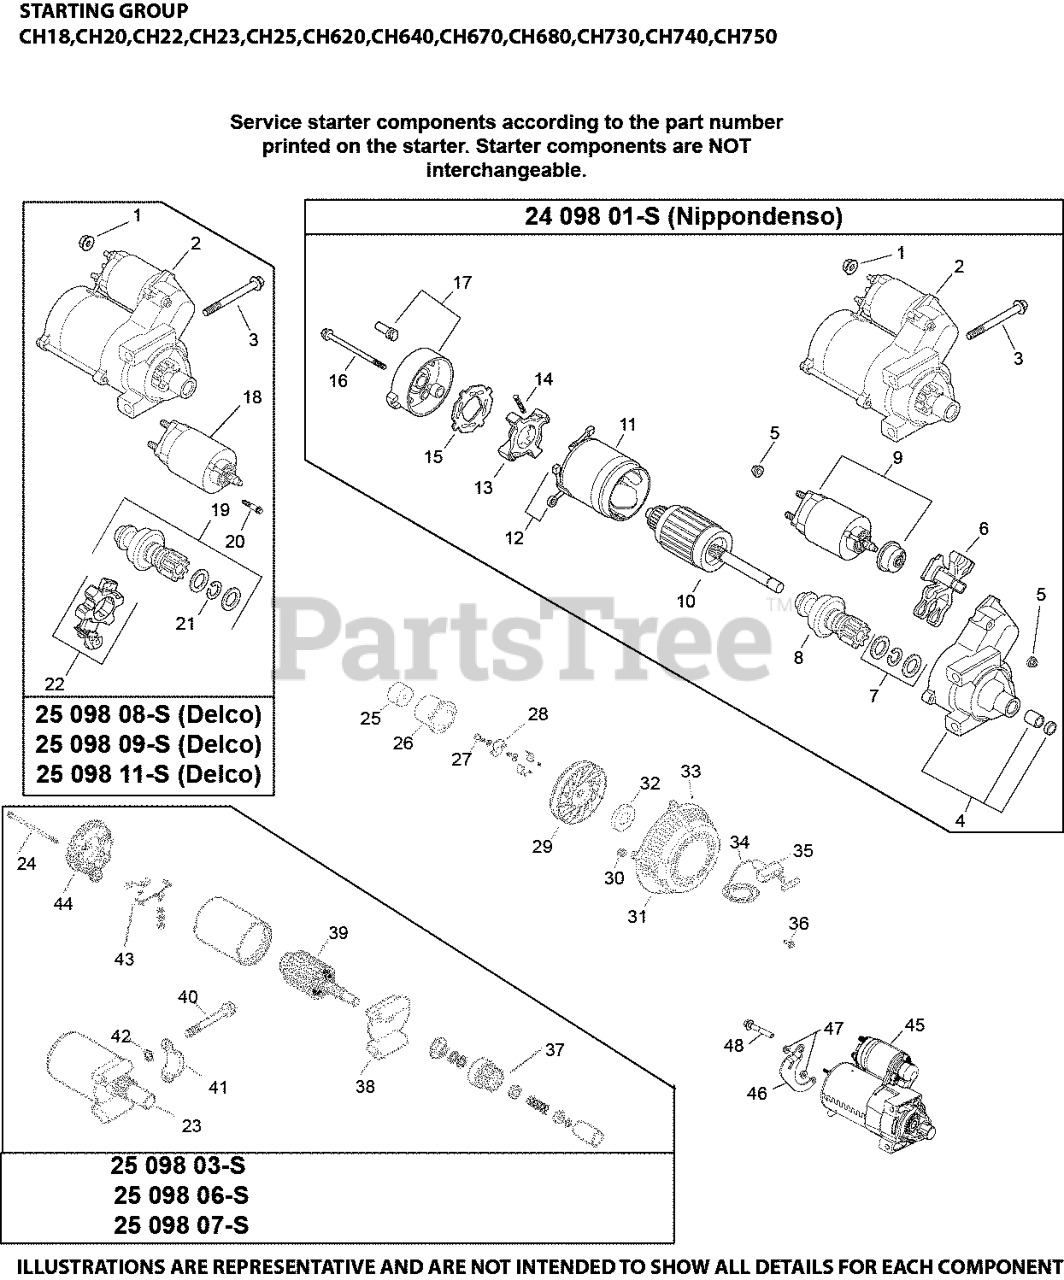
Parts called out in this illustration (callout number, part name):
1	NUT, FLG M8X1.25
2	ELECTRIC STARTER - SOLENOID SHIFT USE 25 098 20-s
3	SCREW, FLG M8X1.25X80
18	KIT, SOLENOID
19	KIT, STARTER PINION
20	SCREW, EXTERNAL TORX HEAD
21	RING, RETAINING-(#DSC)
22	KIT, BRUSH HOLDER
25	SPACER, DRIVE CUP
27	SCREW - DISCONTINUED
28	KIT, DOG REPAIR - (#DSC)
29	PULLEY - (#DSC)
31	HOUSING - DISCONTINUED
32	SPRING & KEEPER - (#DSC)
33	STARTER, RECOIL USE 24 165 03-S
34	ROPE - DISCONTINUED
35	HANDLE, RECOIL STARTER
36	SCREW, SPECIAL HEAD
47	NUT, 1/4-20 GRADE 2
